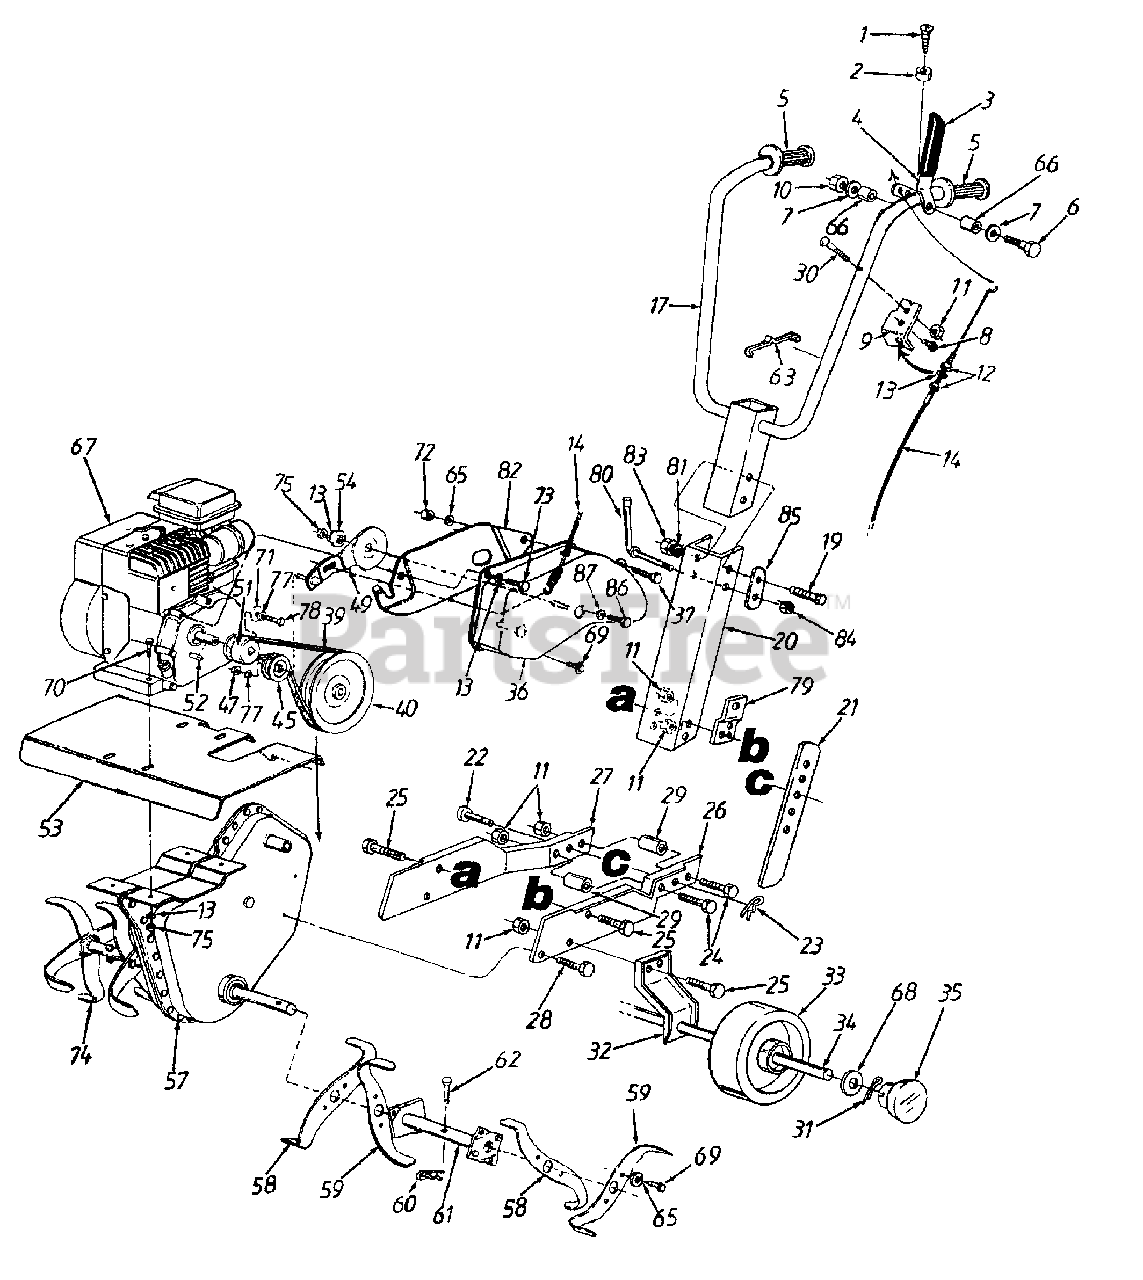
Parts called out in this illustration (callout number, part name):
1	Tap Scr. #10 x 1/2" Lg.
2	Rubber Bumper
3	Vinyl Grip
5	Handle Grip
6	Hex Bolt 1/4-20 x 2" Lg.
7	Fl-Wash. 1/4" I.D.
8	Hex Tap Scr. 1 /4-20 x 1/2" Lg.
9	Cable Bracket
10	Lock Nut 1/4-20 Thd.
11	Lock Nut 5/16-18 Thd.
12	Hex Jam Nut 5/16-24 Thd.
13	L-Wash. 5/16" I.D.
14	Clutch Control Cable
23	Hairpin Cotter
24	Hex Bolt 5/16-18 x 1" Lg.
25	Hex Bolt 5/16-18 x 5/8" Lg.
29	Spacer
30	Hex Bolt 5/16-18 x 1-1/4" Lg.
31	Cotter Pin
34	Axle-Wheel
35	Hub Cap
39	V-Belt
40	Pulley-Chain Case
45	Flat Idler Pulley
47	Hex Jam L-Nut 3/8-24 Thd.
49	Idler Arm Ass'y.
51	Engine Pulley
52	Square Key 3/16" x .75" Lg.
57	Chain Case Ass'y. Comp.
63	Cable Tie-Plastic
65	L-Wash. 1/4" I.D.
66	Spacer
67	Engine
68	Fl-Wash. .4061. D.
69	Tap Scr. 1/4-20 x 1/2" Lg.
70	Hex Bolt 3/8-16
71	Fl-Wash. 3/8" I.D. x 1" O.D.
72	Hex Nut 1/4-20 Thd."
73	Hex Bolt 5/16-24 x .5" Lg.
77	L-Wash. 3/8" I.D."
78	Hex Bolt 3/8-24 x 1" Lg.
81	Fl-Wash. .385" I.D. x .87" O.D.
84	Hex Flange L-Nut 3/8-24 Thd.
85	Retainer Bracket
86	Hex Bolt 5/16-18 x .75" Lg.
87	Fl-Wash .330 .I.D.
